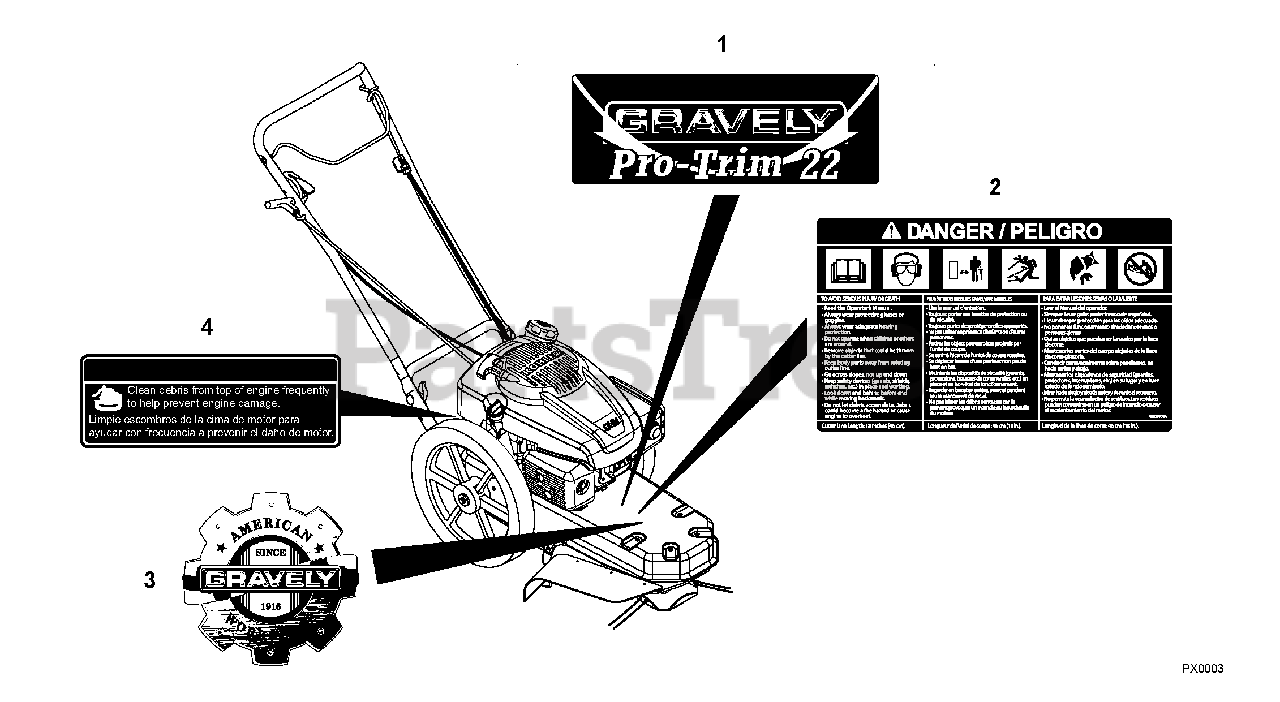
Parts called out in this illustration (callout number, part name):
1	Decal, Gravely Pro-Trim
2	Decal, Danger
3	Decal, Gravely Heritage
4	Decal, Trimmer Debris Warning
